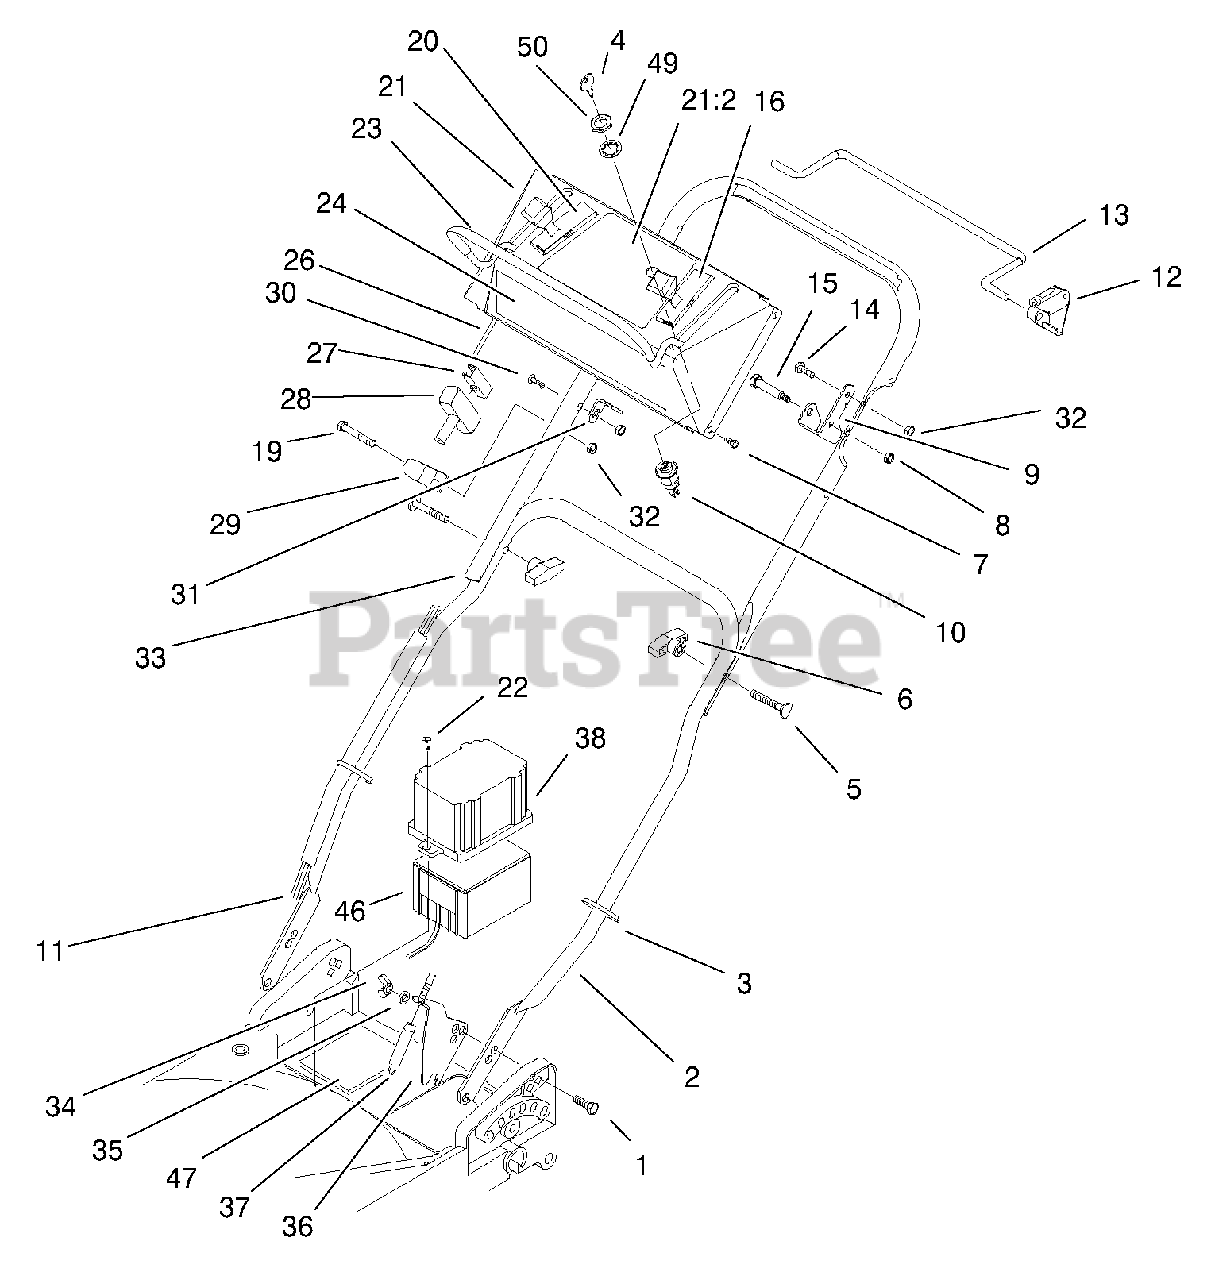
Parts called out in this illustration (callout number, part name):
1	Screw-CARR
2	Handle-Lower
3	Tie Strap
4	Key-Ignition
6	Knob-Handle
8	Nut-Lock, NI
9	Bracket-Stop, Bail
10	Switch-Starter
11	Harness-Wire
12	Stop-Pivot
13	Bail-Control
14	Screw-HH
16	Control ASM-Throttle
19	Screw-HH
20	Control ASM-Ground Speed
21	Control Panel
21:2	Decal-Control Panel
23	Bail-Engine Control
24	Decal-Panel
26	Control ASM, Zone
27	Starter-Clip
28	Handle-Start
29	Rope-Guide
30	Screw-Handle
31	Bracket-Anchor, Cable
32	Nut-Lock, NI
33	Handle-Upper
35	Washer-Lock/Sp
36	Bracket-Traction Cable
37	Cable-Traction
38	Case-Battery
46	Battery Assembly
47	Pad-Battery
49	Washer-Lock/Internal
